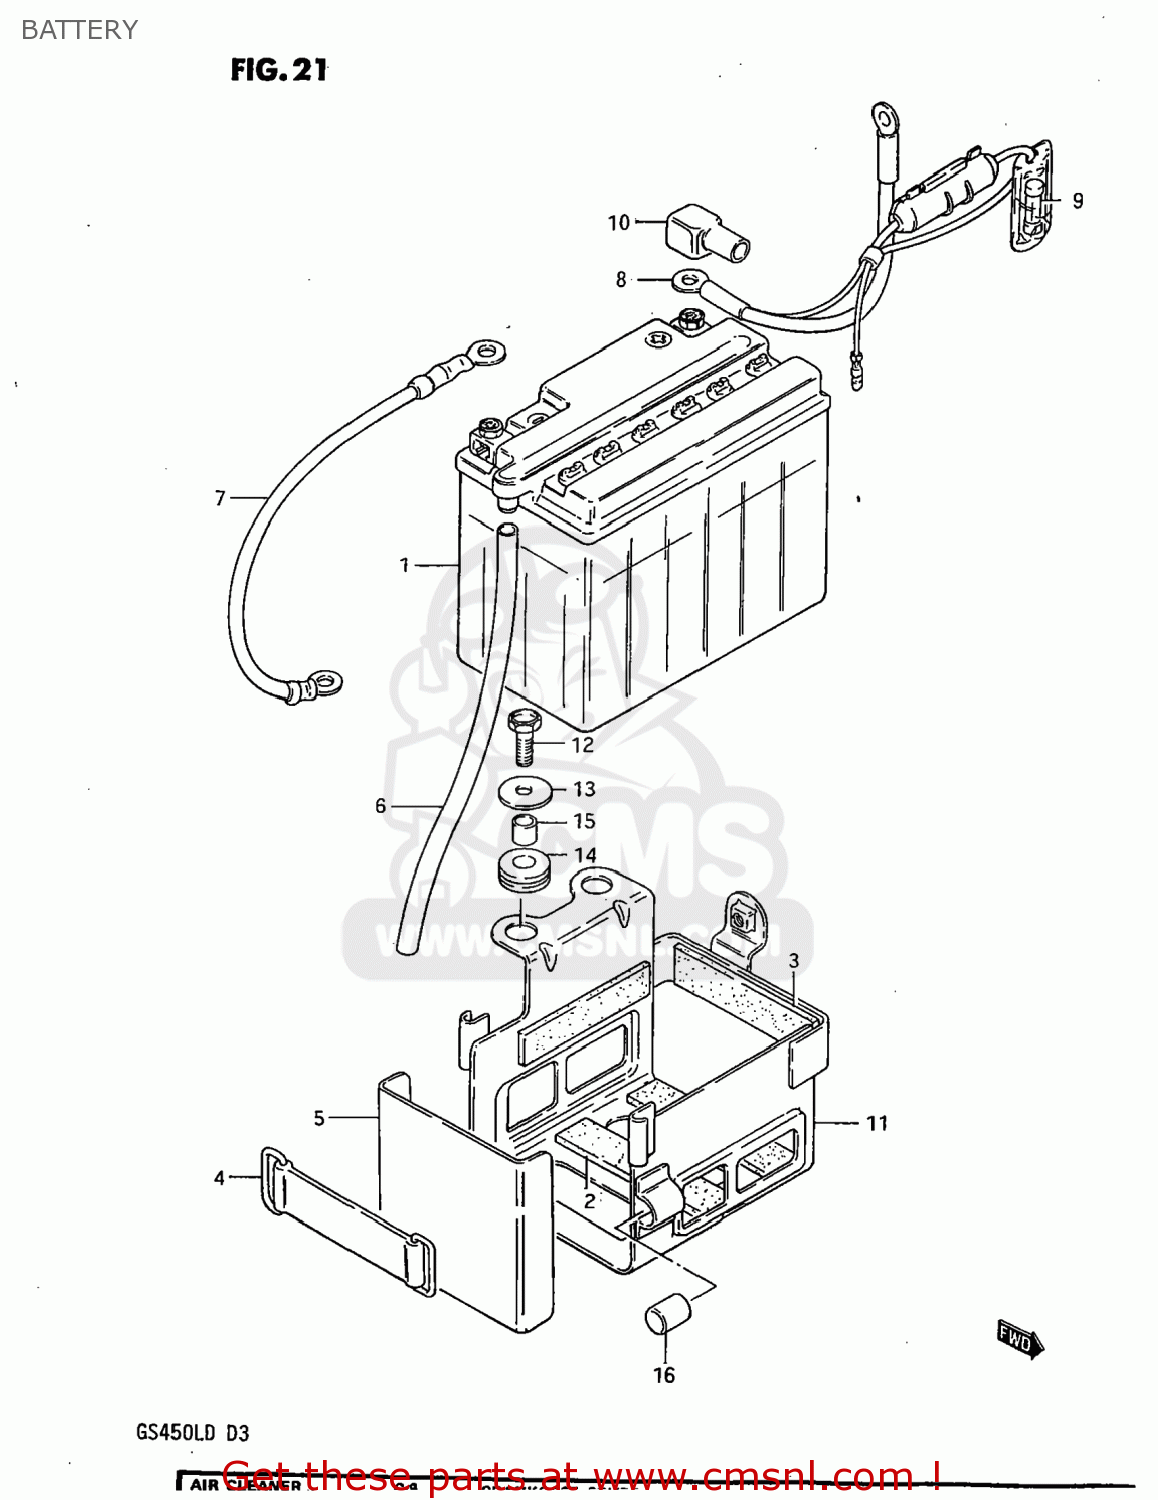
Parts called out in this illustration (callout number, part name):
1	BATTERY ASSEMBLY (12V)
2	PROTECTOR(20X90)X4
3	PROTECTOR,20X9
4	BAND
5	COVER,BATTERY
6	HOSE,BATTERY EXHAUST
7	LEAD WIRE,BATTERY(-)
8	FUSE CASE AND PLUS CABLE
9	FUSE(15A)
10	CAP,TERMINAL
11	HOLDER,BATTERY
12	BOLT
13	WASHER
14	CUSHION
15	SPACER (6.1X9X9)
16	CUSHION
